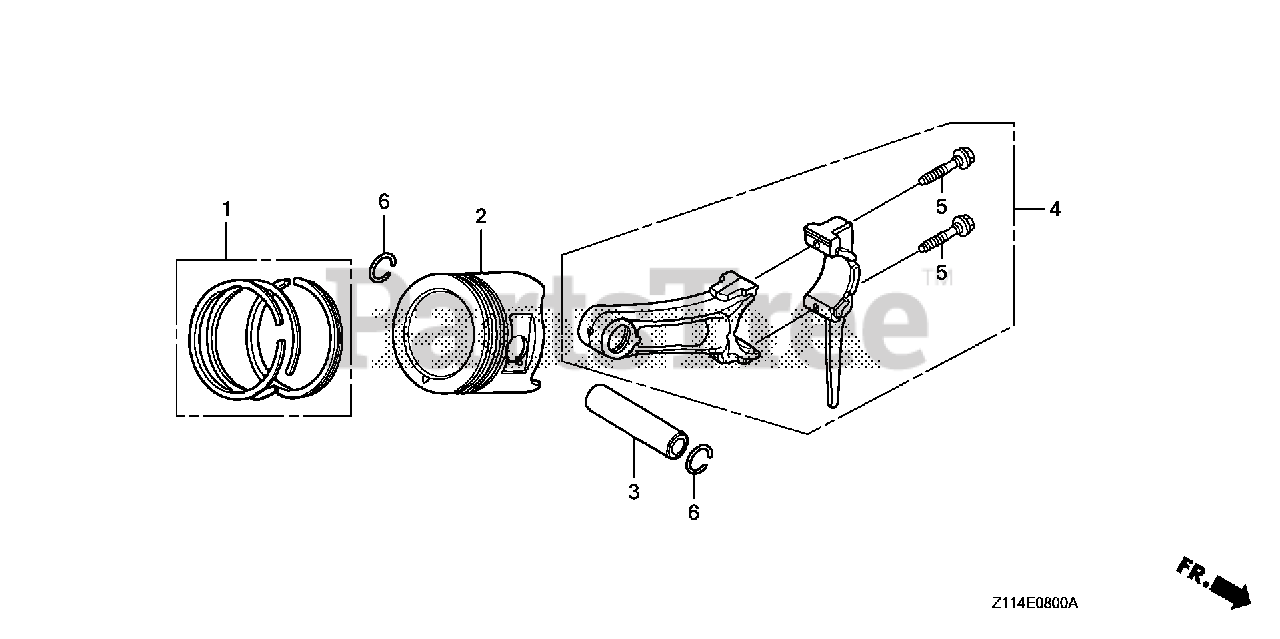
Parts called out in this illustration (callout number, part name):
1	RING SET, PISTON (STD) (TEIKOKU)
1	RING SET, PISTON (0.25) (TEIKOKU)
1	RING SET, PISTON (0.50) (TEIKOKU)
1	RING SET, PISTON (0.75) (TEIKOKU)
2	PISTON (STD)
2	PISTON (0.25)
2	PISTON (0.50)
2	PISTON (0.75)
3	PIN, PISTON
4	ROD ASSY., CONNECTING (0.25 LOWER SIZE)
4	ROD ASSY., CONNECTING (STD)
5	BOLT, CONNECTING ROD
6	CLIP, PISTON PIN (20MM)
